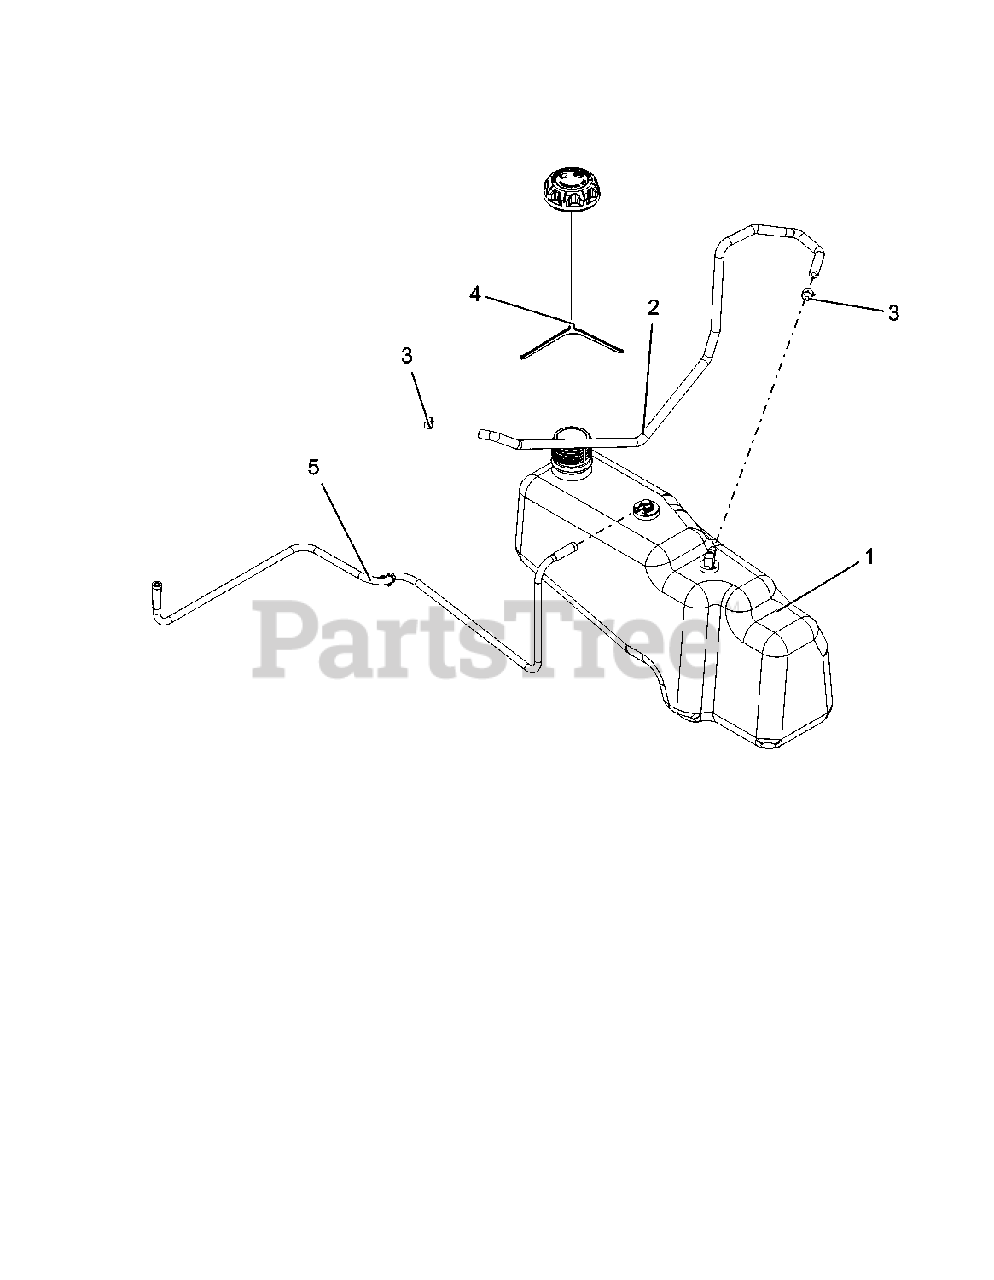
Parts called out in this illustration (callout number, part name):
1	ASM, TANK NON-PERM FUEL
2	HOSE, .25 LOW-PERM BULK GAS-25" LONG
3	CLAMP, FUEL LINE
4	CAP, FUEL VENT-IN 2.25" RATCHET
5	LINE, FUEL VENT KOHLER SMCHOKE
